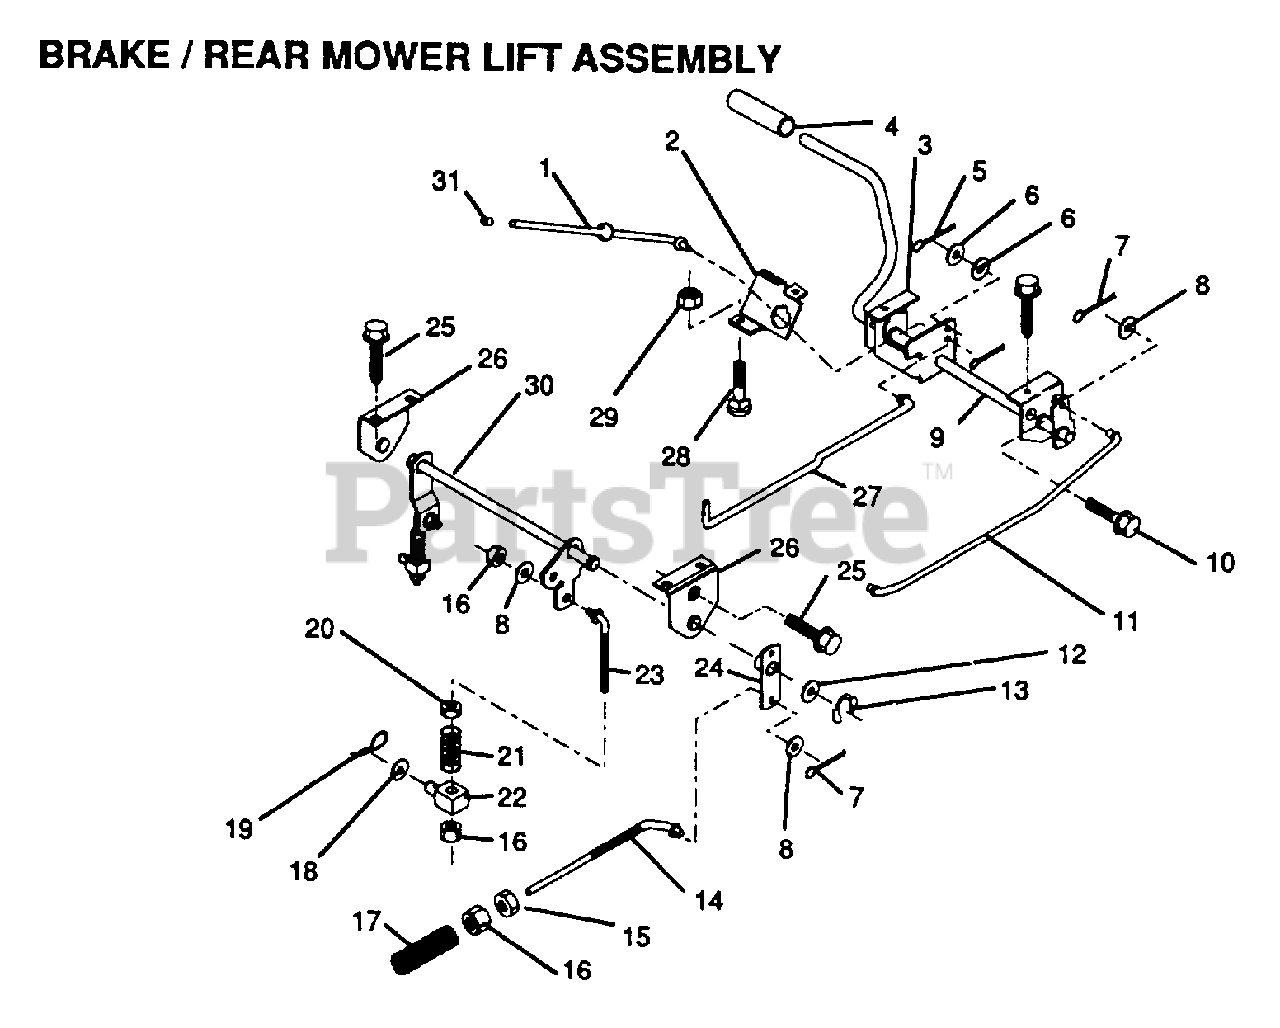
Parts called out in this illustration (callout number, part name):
1	"ROD,PARK BRAKE"
2	"BRKT,PARK BRAKE"
3	"BRKT,CLU PEDAL LH"
4	PEDAL COVER T
6	WASHER
7	COTTER PIN
8	WASHER
10	SCREW LT
11	"ROD,FRT BRAKE"
12	WASHER T
13	KLIP RING
15	NUT
17	SPRING ROD LT
18	WASHER
19	SPRING.RETAINER
20	LOCKNUT
21	SPRING ROD LT
23	"LINK.LIFT.3.5"""
24	BRAKE PIVOT ARM
25	SCREW LT
26	"BRKT,LIFT SHAFT"
27	"ROD,CLUTCH"
30	REAR MOWER LIFT
31	PLUNGER CAP T
